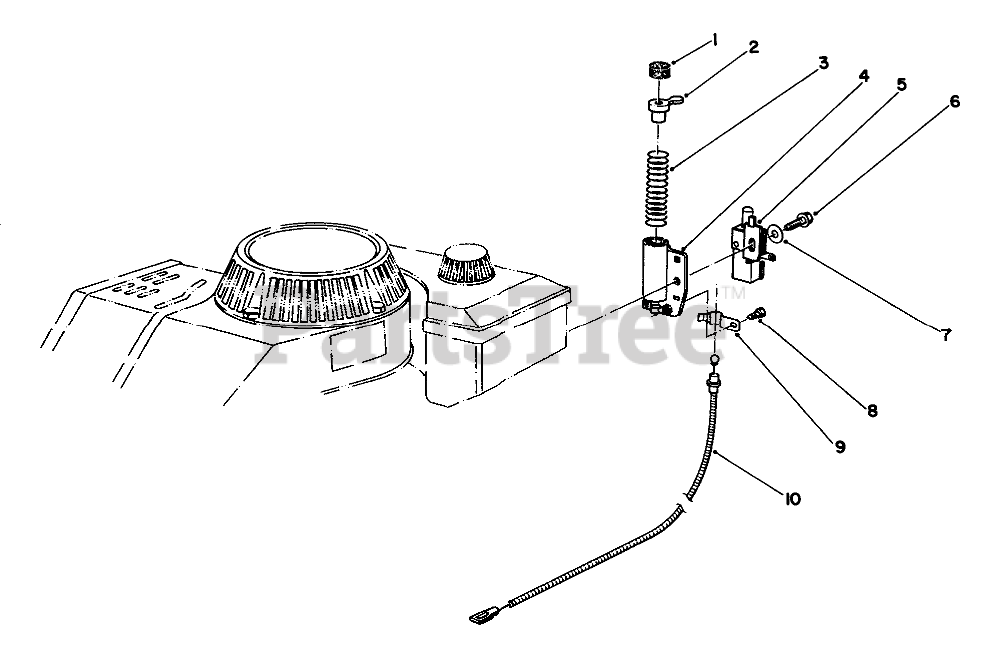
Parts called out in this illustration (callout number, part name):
1	Pad-Friction
2	Plunger Assembly (Incl. Ref. #1)
3	COMP SPRING
4	TUBE W A
5	PUSH BUTTON SWITCH
6	THO FORM SCREW M6 X 1
7	WASHER-FLAT
8	SCREW
9	CABLE CLAMP
10	BRAKE CABLE-SUZUKI
